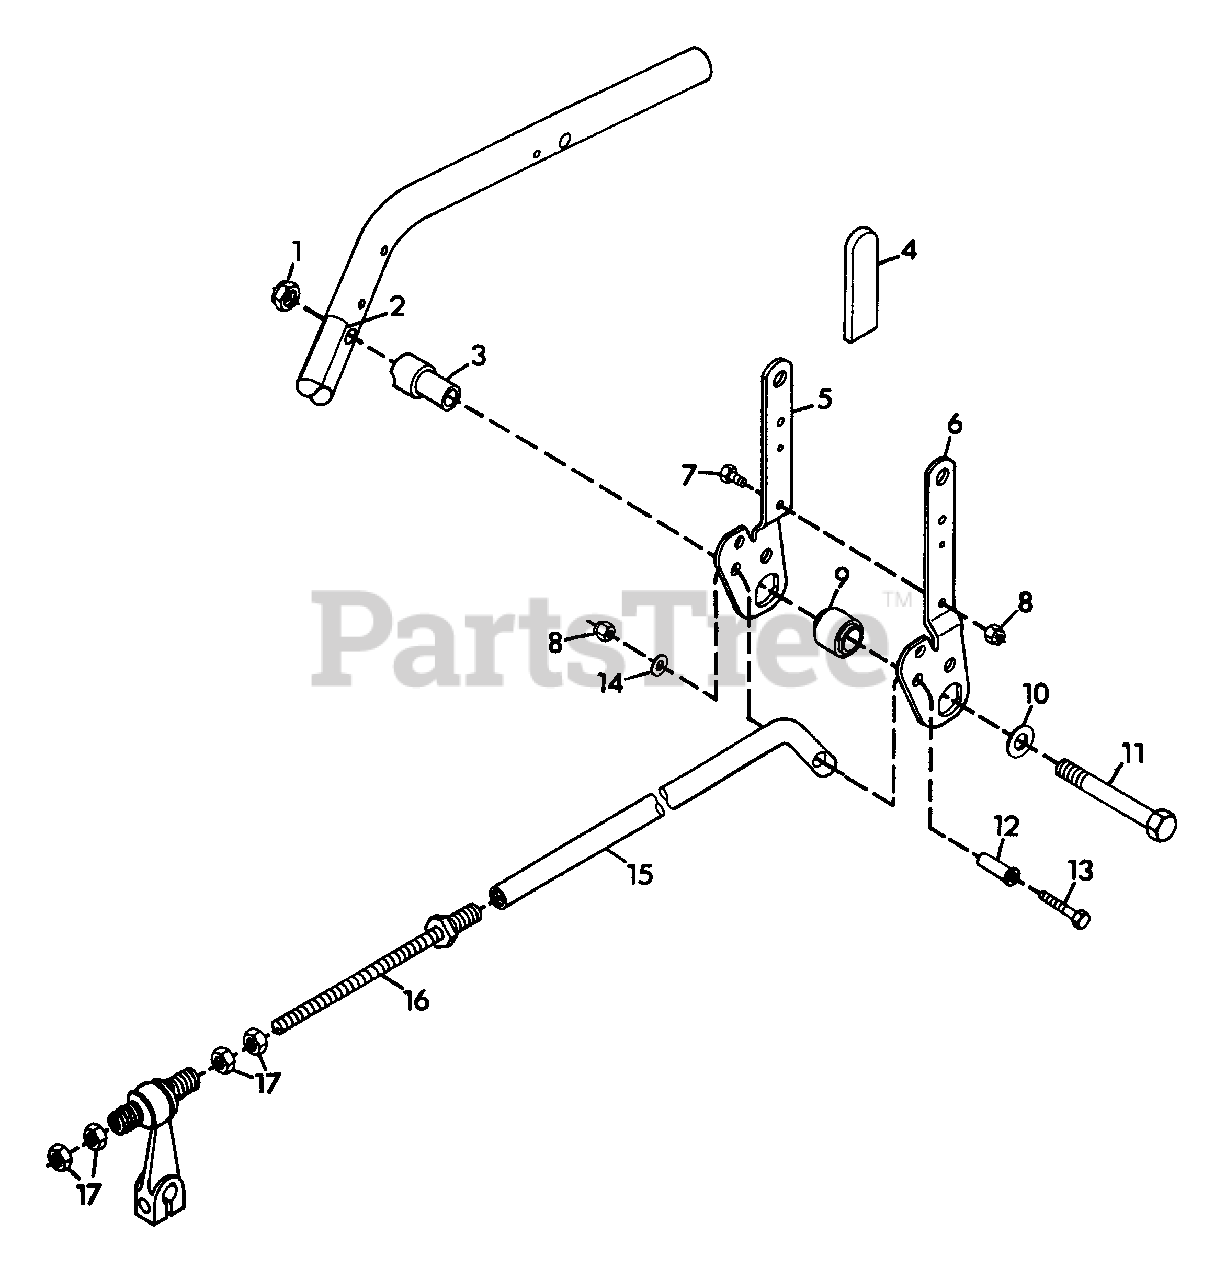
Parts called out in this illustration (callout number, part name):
1	Nut, Lock 1/2-13 E.T.
2	Decal, Gear Shift
3	Pivot, Hand Lever L.H.
4	Grip, Handle
5	Handle, Control R.H.
6	Handle, Control L.H.
7	Bolt, Hex 1/4-20 x .625
8	Nut, Lock 1/4-20
9	Bushing, Handle
10	Washer, Flat .531 x1.062 x .095
11	Bolt, Hex 1/2-13 x 3.50
12	Bushing, Operator Presence Handle
13	Bolt, Hex 1/4-20 x 1.50
14	Washer, Flat .281 x .625 x .065
15	Rod, Control Hi-Lo
16	Rod, Control Extension
17	Nut, Jam 3/8-16 Hex
